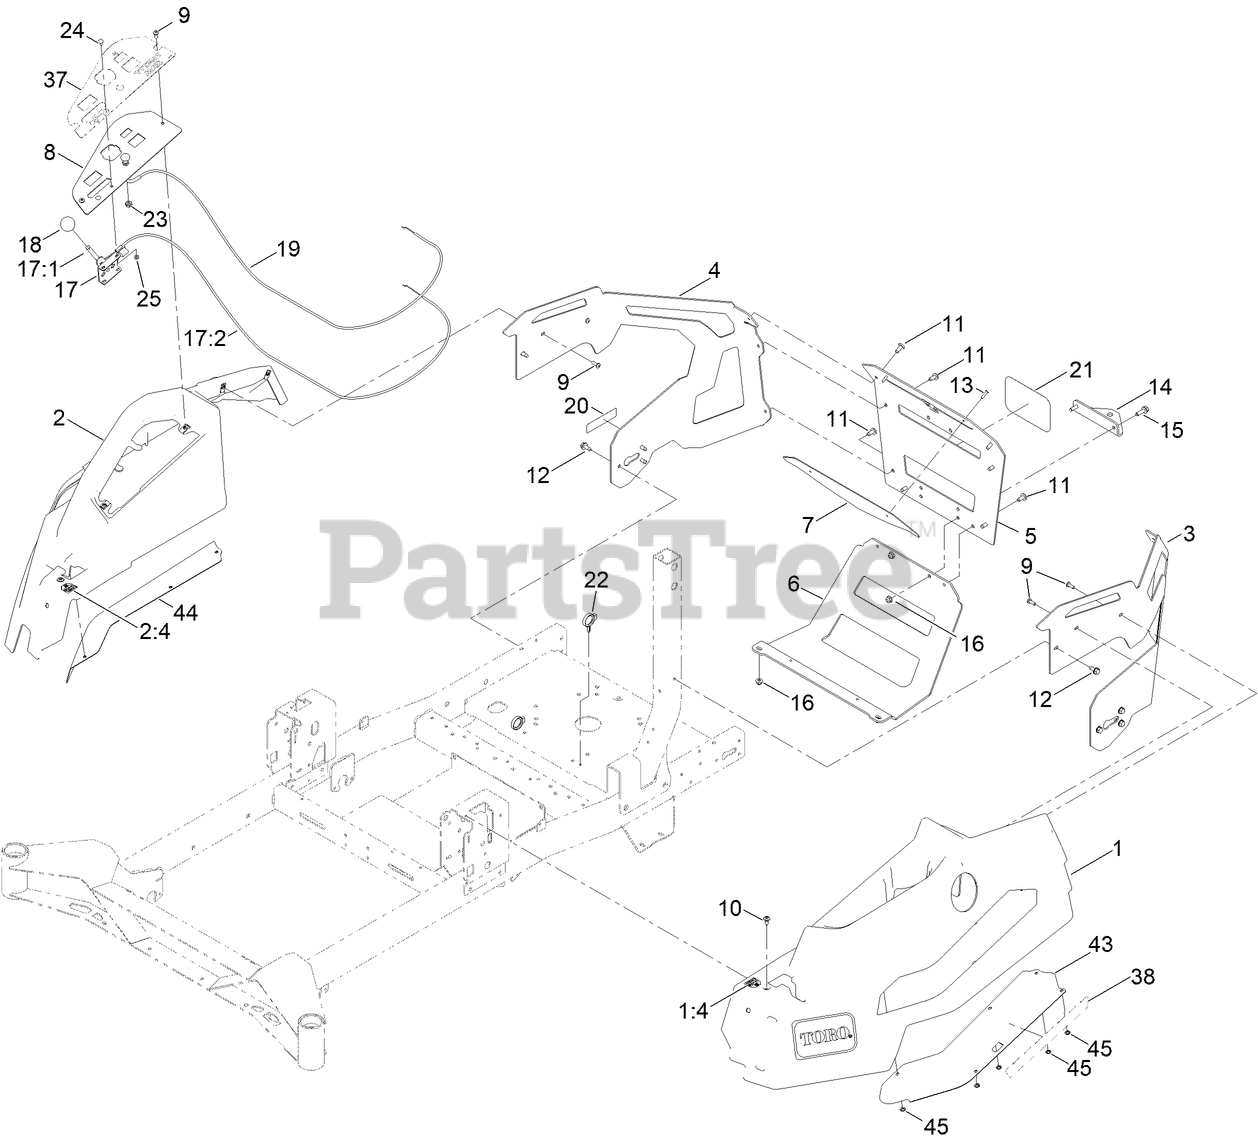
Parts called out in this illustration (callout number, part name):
1	TITAN MAX LH POD ASM
1:4	DECAL-CONTROL LEVER, LH
2	TITAN MAX RH POD ASM
2:4	DECAL-CONTROL LEVER, RH
3	GUARD-ENGINE, LH
4	GUARD-ENGINE, RH
5	GUARD-ENGINE
6	GUARD-MUFFLER
7	PLATE-BACKER
8	PANEL-CONTROL
9	SCREW-PH
10	SCREW-SHOULDER
12	SCREW-HWHTF
13	RIVET-TRIFOLD
14	BRACKET-HITCH
15	SCREW-HHF
16	NUT-HF
17	THROTTLE CONTROL ASM
17:1	LEVER-THROTTLE
18	KNOB-BALL
19	CABLE-CHOKE CONTROL
20	DECAL-SPARK ARRESTER
21	DECAL
22	CLAMP-HOSE
23	NUT-HJ
24	BOLT-CARR
25	NUT-LOCK, NI
37	DECAL-PANEL, CONTROL
38	DECAL-TITAN MAX
43	PLATE-POD, LH
44	PLATE-POD, RH
45	NUT-PUSH
